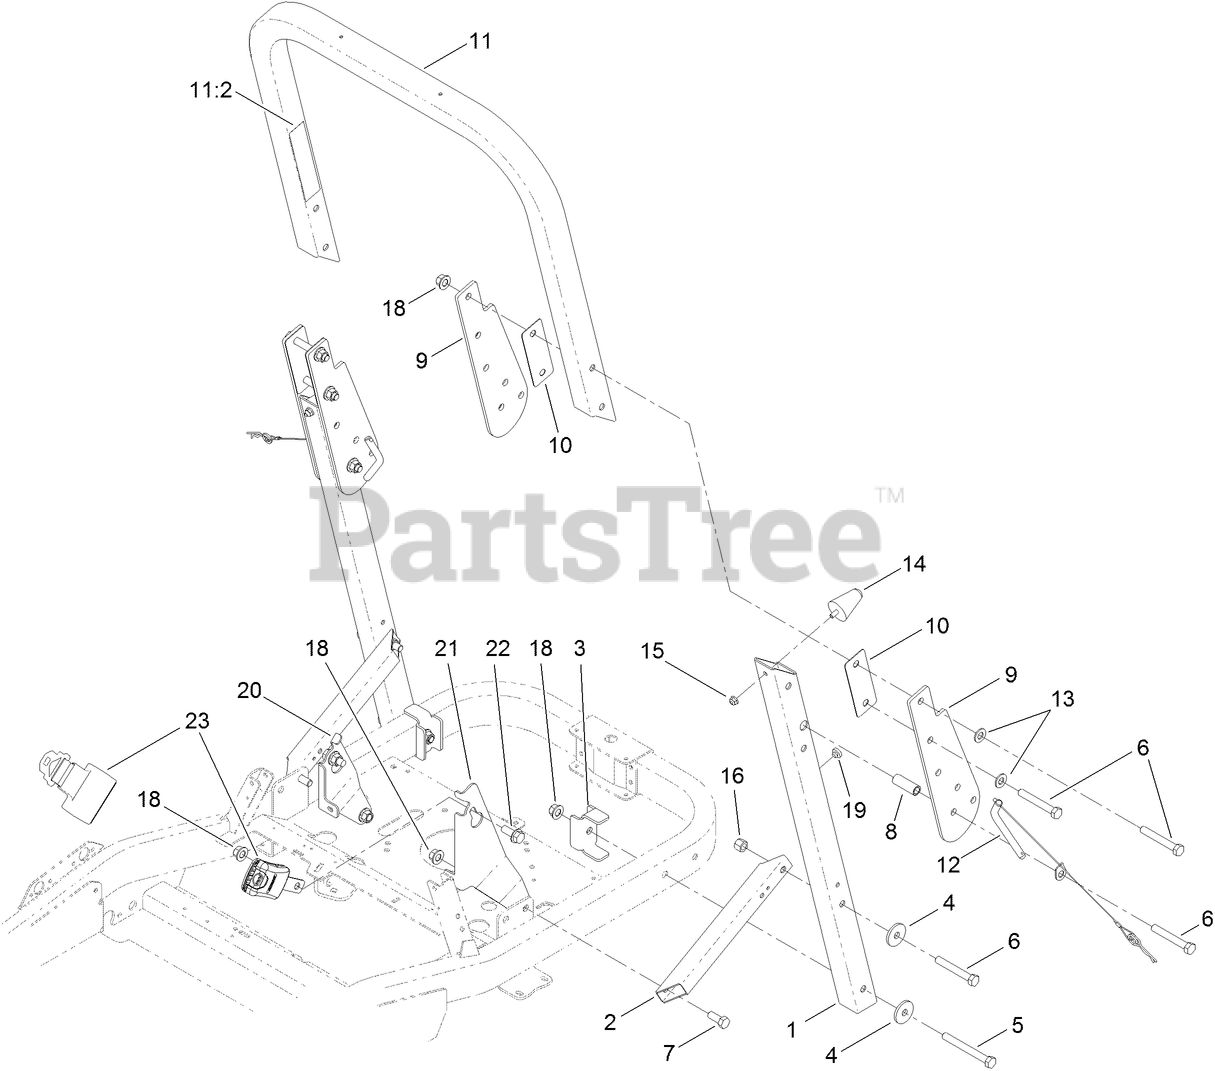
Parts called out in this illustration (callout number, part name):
1	TUBE-ROPS, LOWER
2	TUBE-SUPPORT, ROPS
3	BRACKET-REINFORCING
4	WASHER-THRUST
5	SCREW-HH
6	SCREW-HH
7	SCREW-HH
8	SPACER
9	BRACKET-PIVOT, ROPS
10	SPACER-ROPS
11	UPPER ROPS ASM
11:2	DECAL-WARNING
12	PIN-ROPS W/ LANYARD
13	WASHER-FLAT
14	BUMPER-RUBBER
15	NUT-HF, NI
16	NUT-HEX
18	NUT-LOCK
19	BUMPER
20	BRACKET-BELT, SEAT
21	BRACKET-BELT, SEAT
22	SCREW-HHF
23	SEAT BELT KIT
